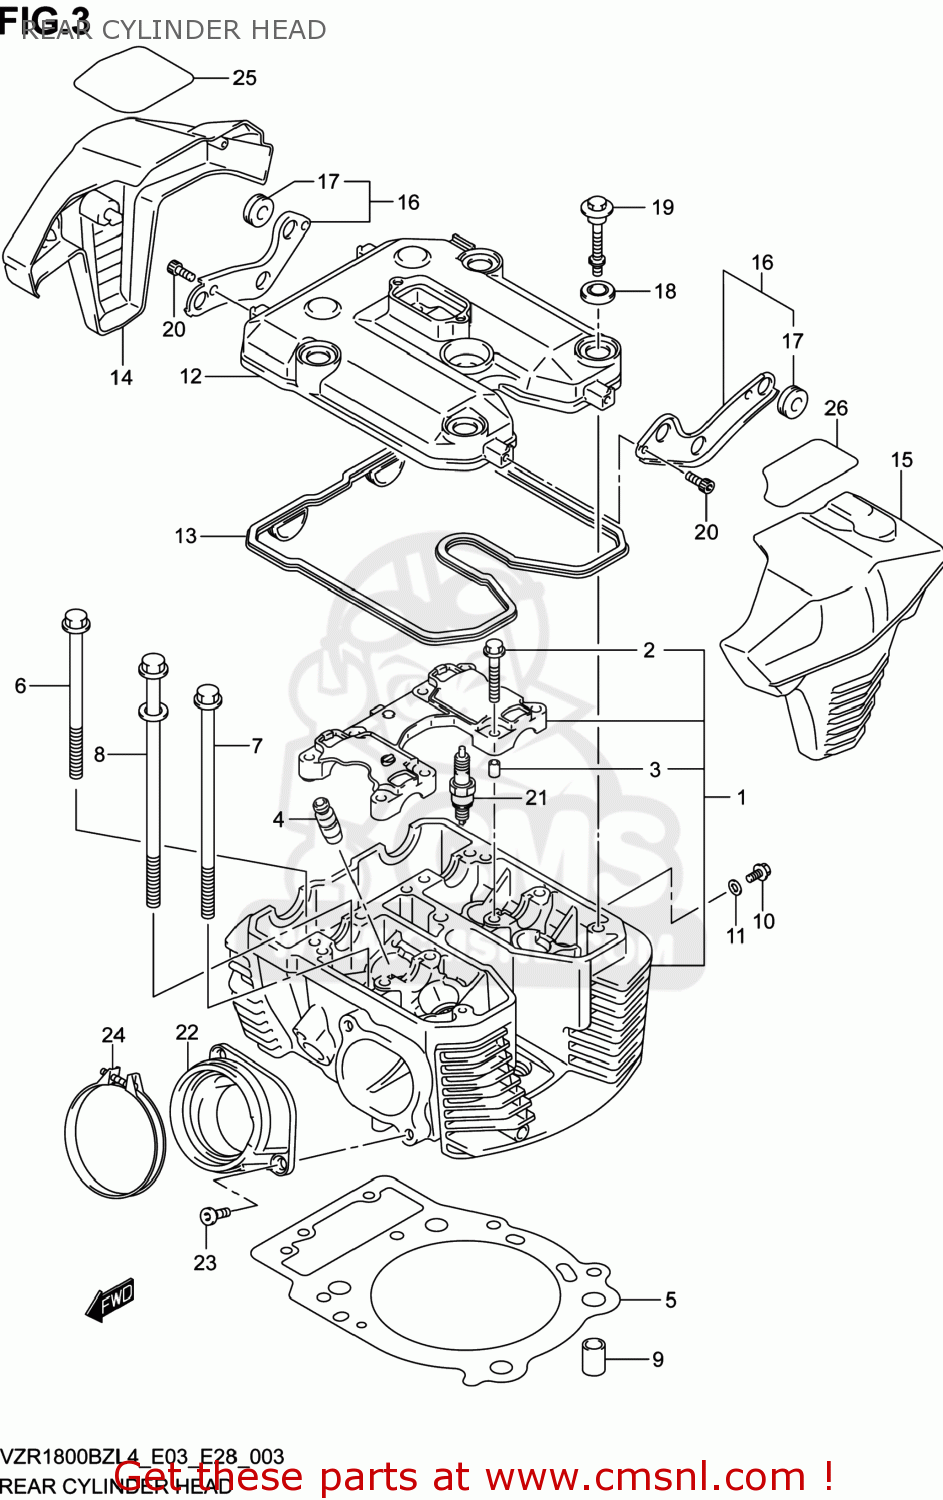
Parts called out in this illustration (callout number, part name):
1	HEAD ASSY,CYLINDER RR
2	BOLT(6X39)
3	PIN(6.2X8X11)
4	GUIDE,VALVE
5	GASKET,CYLINDER HEAD RR (NAS)
6	BOLT(8X140)
7	BOLT(8X180)
8	BOLT(10X19)
9	PIN
10	BOLT(6X12)
11	GASKET(5.8X13X1.2) (NAS)
12	COVER,CYLINDER HEAD
13	GASKET,CYL HEAD COVER (NAS)
14	CAP,CYL HEAD COVER NO.1
15	CAP,CYL HEAD COVER NO.2
16	BRACKET,HEAD COVER CAP
17	CUSHION
18	CUSHION,HEAD COVER BOLT
19	BOLT(6X52)
20	BOLT
21	PLUG,SPARK(CR8EK)
22	PIPE ASSY,INTAKE
23	BOLT(6X20.5)
24	CLAMP,INTAKE PIPE
25	PROTECTOR,HEAD COVER CAP NO.1
26	PROTECTOR,HEAD COVER CAP NO.2
